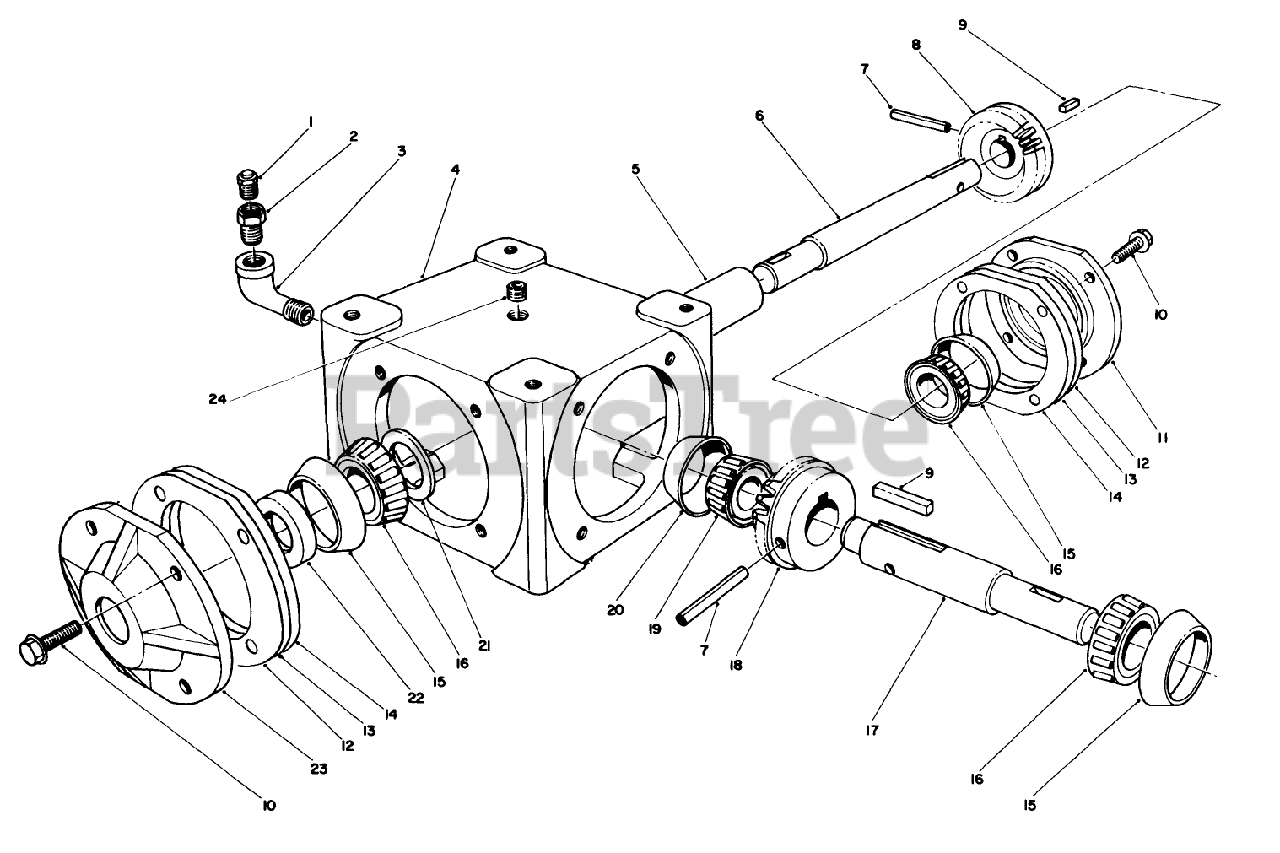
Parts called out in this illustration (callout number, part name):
1	Valve
2	BUSHING
3	Elbow-Street
4	HOUSING
5	SPACER
6	SHAFT
9	Key
10	SCREW-HH (OBS, C/R TO 3234-5)
12	GASKET
13	GASKET
14	GASKET
15	Cup
16	Cone
17	SHAFT
19	Cone
20	Bearing Cup
21	WASHER
22	Seal
24	PLUG (OBS, C/R TO 281-10)
